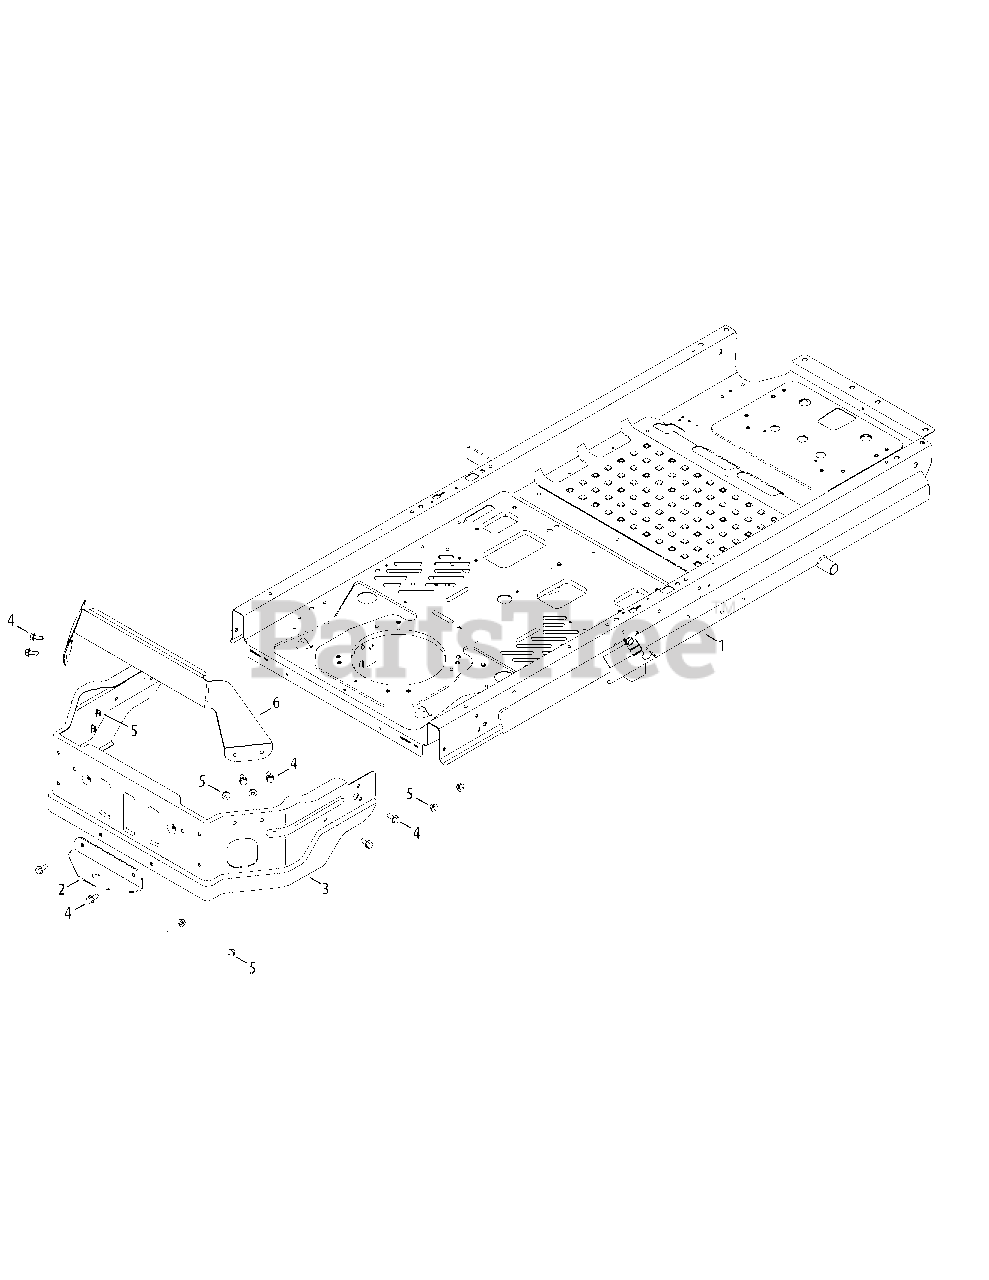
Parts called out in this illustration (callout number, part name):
1	Frame Assembly
4	Screw, 5/16-18, Hexflange
5	Flange Lock Nut, 5/16-18
6	Upper Bumper Bracket
